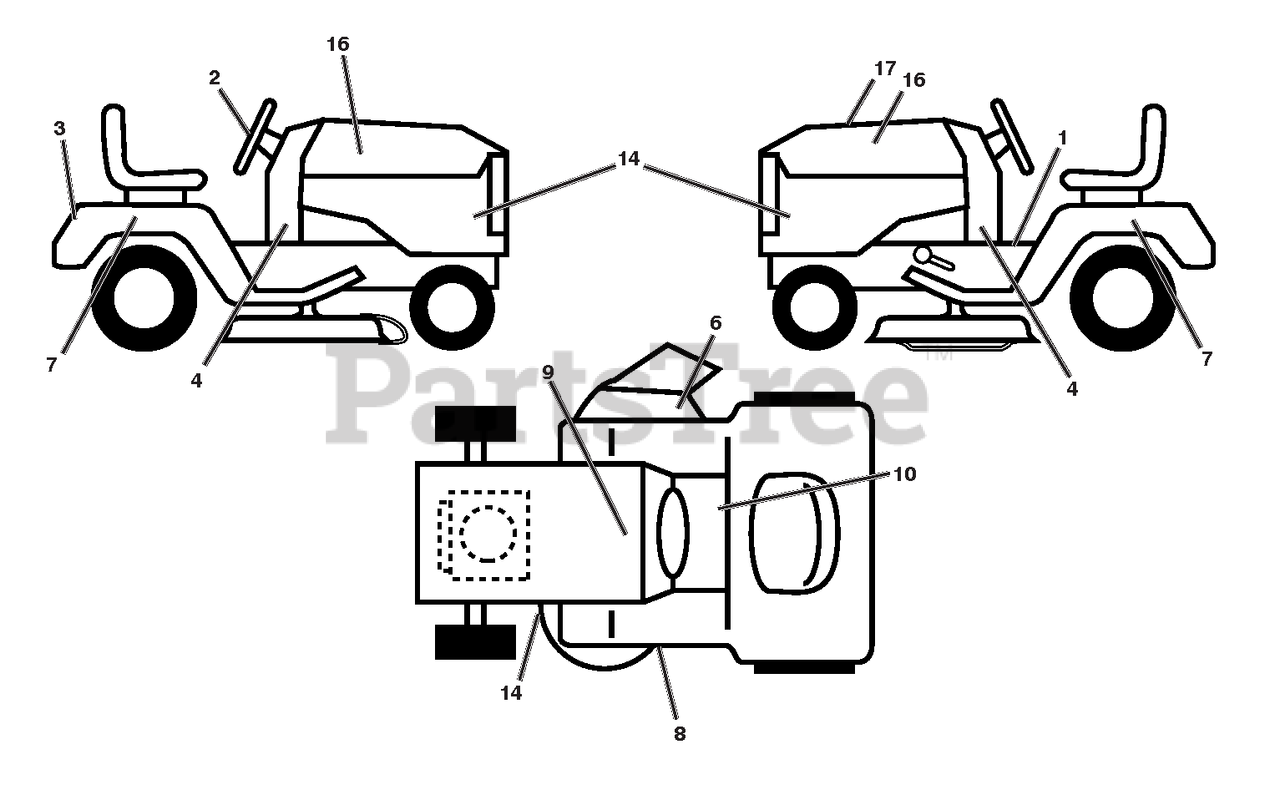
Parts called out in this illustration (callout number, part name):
1	DECAL.WARNING
2	DECAL.WHEEL.STEER.ARIENS
3	DECAL.FENDER.REAR.ARIENS
4	DECAL DASH LOWER
5	DECAL.MOWER.CAUTION.TENSION.AR
6	DECAL.MOWER.WARN.KEEP HAND AWY
7	DECAL.FENDER.SIDE.HYDRO.ARIENS
8	DECAL.MOWER.SCH.48/54.PREM.
9	DECAL.BAT.DAN/POI P/L SYM.WPN
10	DECAL.FENDER
14	DECAL.SDPNL.PWRDBY KOHL.ARIENS
16	DECAL.HOOD.RH.PRECISION.ARIENS
17	DECAL.REPLACEMENT
